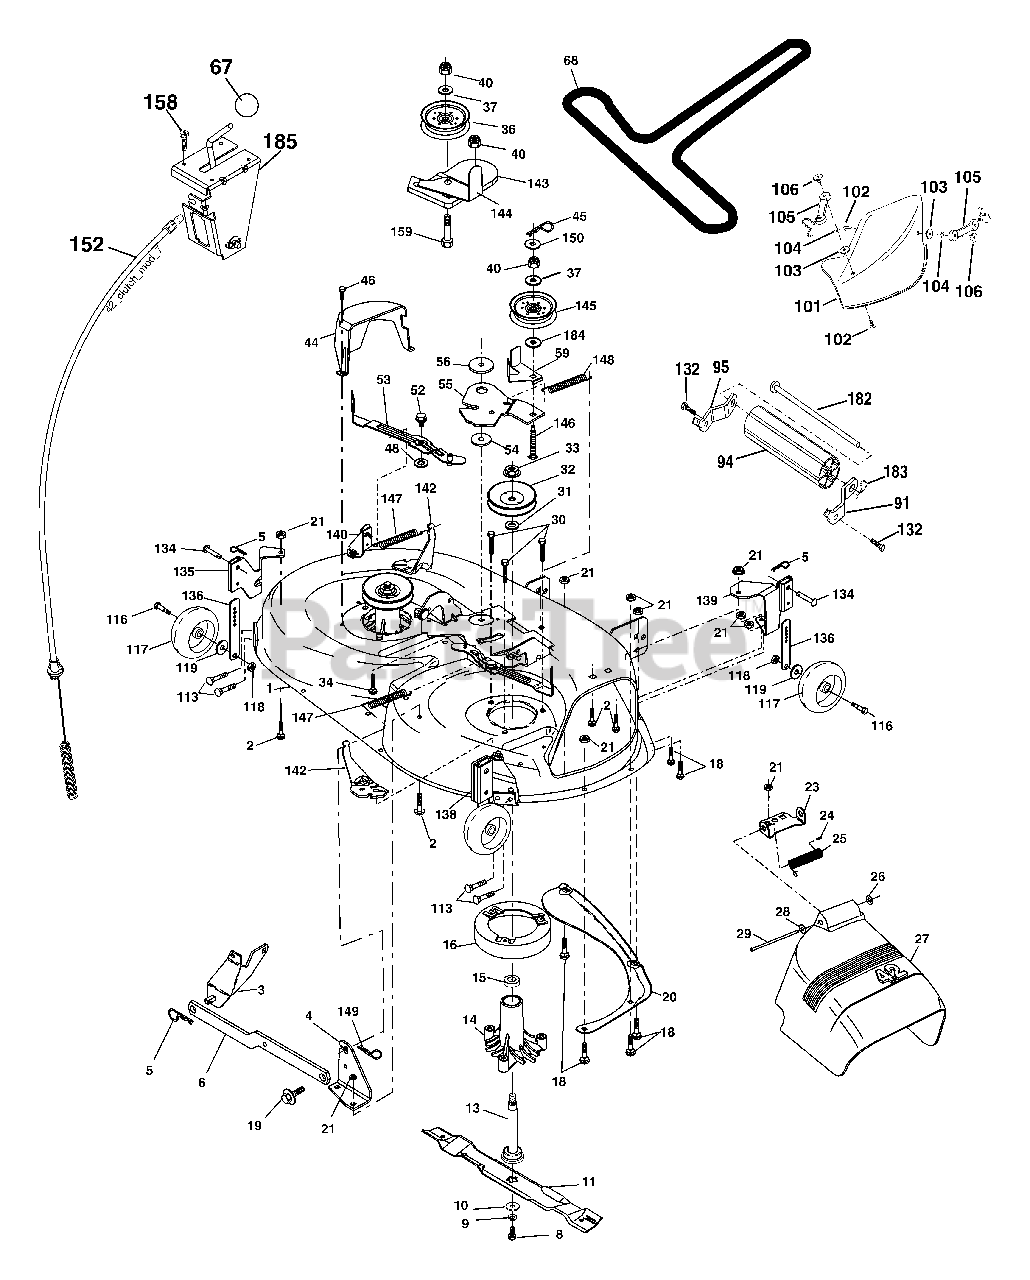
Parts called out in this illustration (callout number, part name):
1	Mower Deck Assembly, 42"
2	Bolt
3	Bracket Asm Fr. Sway Bar 3/42
4	Bracket Asm Deck 42" Sway Bar
5	Retainer Spring
6	Bar Sway Deck
8	Bolt 3/8-24 x 1.25 Gr. 8 patched
9	Washer, Lock
10	Washer, Hardened
11	Blade, Mulching 42" Std
11	Blade Mulching 42" Premium
11	Blade Mower 42" Hi-Lift
13	Shaft Assembly, Mandrel, Vented
14	Housing, Mandrel, Vented
15	Bearing, Ball, Mandrel
16	Stripper, Mandrel Deck
18	Bolt, Carriage 5/16-18 x 5/8
19	Bolt, Shoulder
20	Baffle, Vortex
21	Nut
23	Bracket, Deflector Mower 42"
24	Cap, Sleeve 80 x 112 Blk Mower
25	Spring, Torsion, Deflector 2 52
26	Nut, Push Phos & Oil
27	Shield, Deflector 42" Blk
28	Washer 11/32 x 5/8 x 16 Ga.
29	Rod, Hinge 42" 6 75 W/G
30	Screw Thdrol
31	Washer, Spacer Mower Vented
32	Pulley, Mandrel
33	Nut, Toplock
34	Bolt Carr SH 3/8-16 x 1-1/2 Gr.5
36	Pulley, Idler, Flat
40	Nut Lock 3/8-16
44	Guard, Mandrel, LH
45	Retainer
46	Screw, Thdrol 1/4-20 x 5/8 T
48	Washer, Hardened
52	Bolt, Shoulder 5/16-18 unc
53	Arm Assembly, Pad, Brake
54	Washer, Hardened
55	Arm, Idler
56	Spacer, Retainer
59	Guard TUV Idler
67	Knob Round
68	V-Belt, 42" Mower
91	Bracket Asm Noseroller LH
92	Nut Lock Hex w/Ins 3/8-16 unc
94	Roller Nose 38 & 42
95	Bracket Asm Noseroller RH
101	Mulcher Cover
102	Screw, Pan Hd Phillip 10-24 x 5/8
103	Washer, Flat
104	Washer, Lock
105	Latch Assembly
106	Nut, Weld
113	Screw 5/16-18 x 3/4
116	Bolt, Shoulder
117	Wheel, Gauge
118	Nut Centerlock 3/8-16
119	Washer 3/8 x 7/8 x 14 Ga.
129	Washer 13/32 x 13/16 x 12 Ga.
130	Bolt Fin HEx 3/8-16 unc x 1 Gr. 5
131	Bolt RDHD SQNK 3/8-16 unc x 1
132	Screw 3/8-16 x .75
134	Pin Head Rivet
135	Bracket Asm. Whl Ga. R LH
136	Bar Adjusting Gauge Wheel
138	Bracket Asm Whl Ga. R RH
139	Bracket Asm. Whl Ga. F RH
140	Bracket Asm Whl Ga. F LH
142	Arm Spring Brake Mower
143	Bracket Arm Idler 42"
144	Keeper Belt 42" Clutch Cable
145	Pulley Idler Flat
146	Bolt Carriage Idler
147	Spring Extension
148	Spring Return Idler
149	Retainer Spring Yellow
150	Washer 9/32 x 3/4 x 10 Ga.
152	Clutch Cable 42"
158	Screw Hex Thd Cut 1/4-20 x 1/2
159	Bolt Rdhd Sqn 3/8-16 unc x 1-3/4
182	Rod Roller Nose
183	Retainer Spring
184	Washer 13/32 x 7/8 x 10 Ga.
185	Head Asm Cable Clutch
